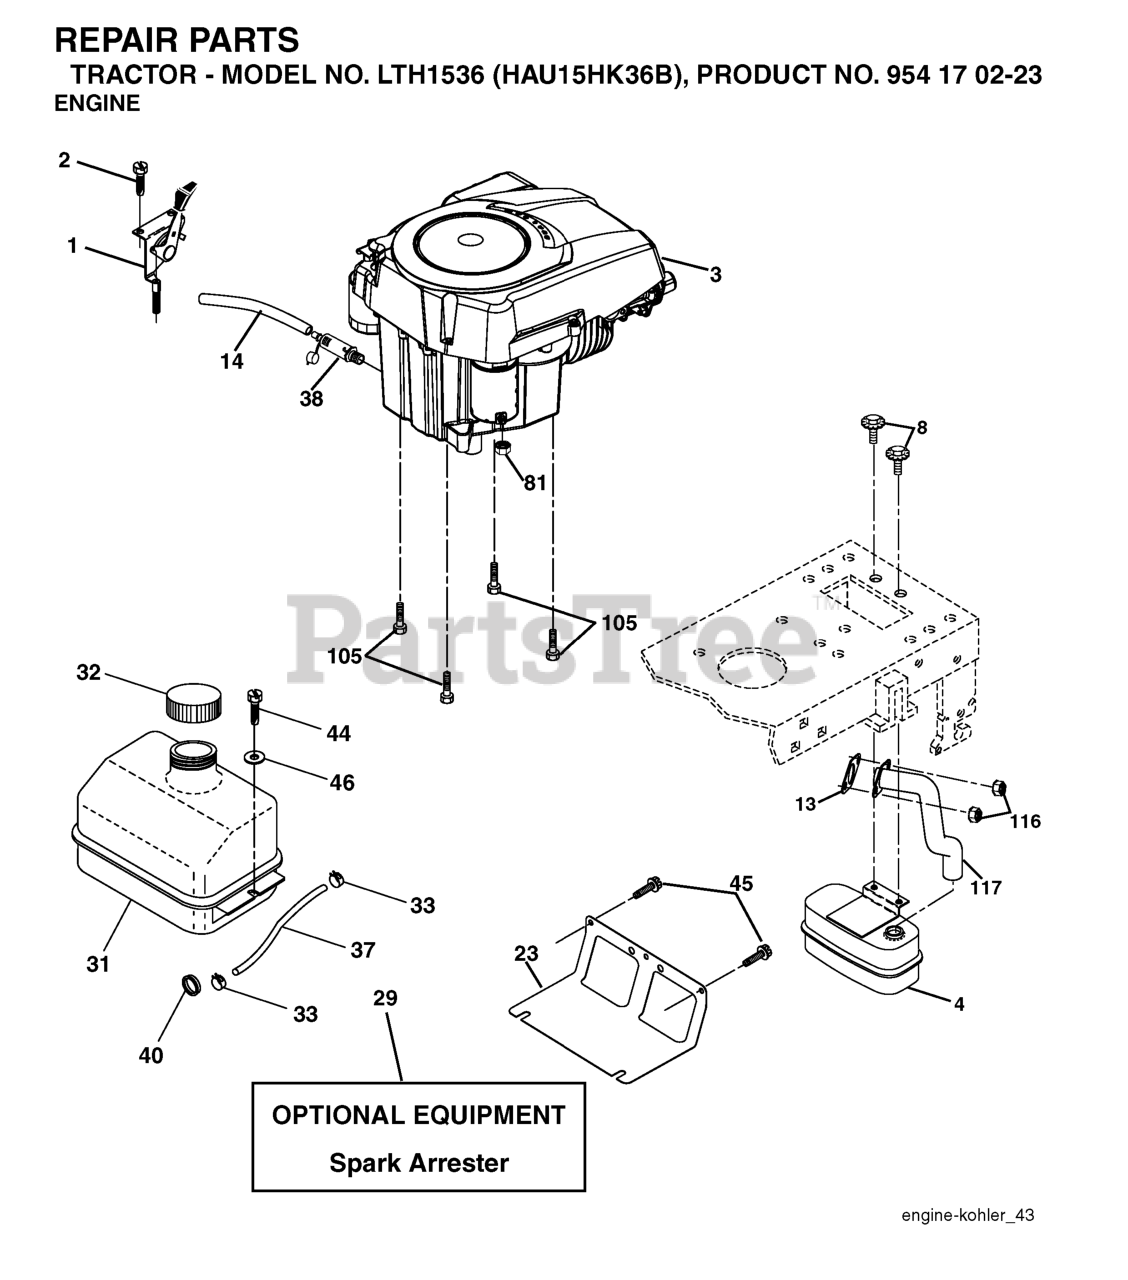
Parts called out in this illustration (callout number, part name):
1	CONTROL.THROTTLE.LT/YT
2	SCREW
4	MUFFLER.SINGLE.CYL.KOHL/B&S
8	BOLT.5/16-18UNCX3/4 W/SEMS.BLK
13	GASKET.EXHAUST.KOHLER
14	TUBE, DRAIN OIL ASM.
23	SHIELD.BROWNING.DBR.GUARD
29	KIT.SPARK ARRESTOR 794945 B&S
31	TANK.ASM.FUEL.FRONT.W/CAP
32	FUEL CAP
33	HOSE CLAMP
37	LINE.FUEL.20
38	PLUG DRAIN OIL EASY
40	BUSHING.SNAP.NYL.BLK.
44	SCREW HEXWSHR 1/4-20X3/4
45	SCREW, 3/8-16X3/4
81	NUT
105	SCREW 3/8-16X1
116	NUT.HEX.FLANGE.TOPLOCK
117	RP.TUBE.EXHAUST.KOHL.COURAGE
